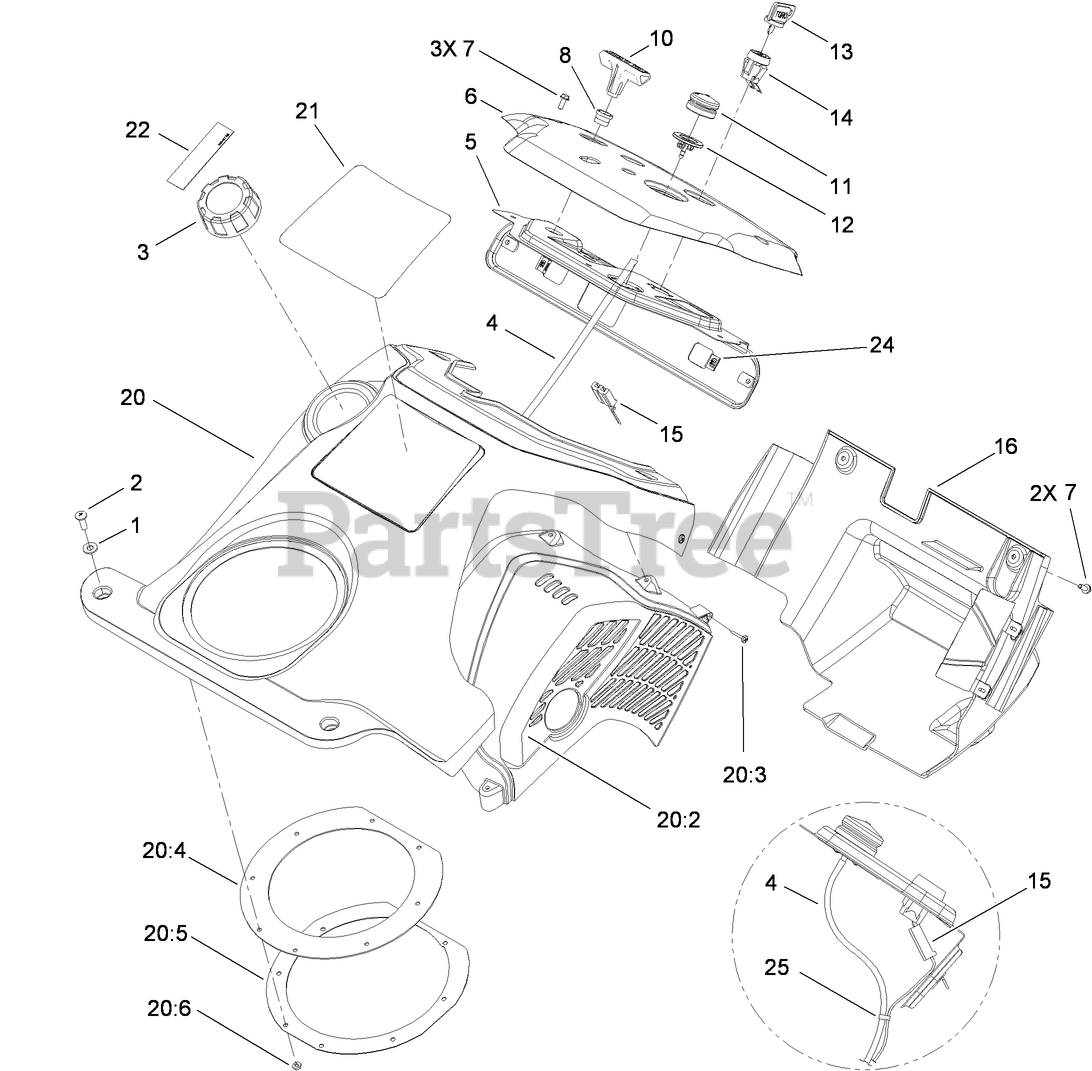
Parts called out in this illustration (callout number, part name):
1	WASHER-FLAT
2	SCREW-PPH
3	GAS CAP ASM
4	HOSE-PRIMER
5	PANEL-SUPPORT, CONTROL
6	PANEL-CONTROL
7	SCREW-HWH
8	GUIDE-ROPE, STARTER
10	HANDLE-STARTER
11	BULB-PRIMER
12	BODY-PRIMER
13	KEY-IGNITION
14	SWITCH
15	CONNECTOR-BODY
16	LOWER SHROUD/BAFFLE ASM
20	UPPER SHROUD ASM
20:2	SHIELD-HEAT
20:3	SCREW-PPH
20:4	SEAL-CHUTE
20:5	RETAINER-SEAL, CHUTE
20:6	PALNUT
22	TAPE-MIX, OIL
24	NUT-SPEED
25	TIE-CABLE
